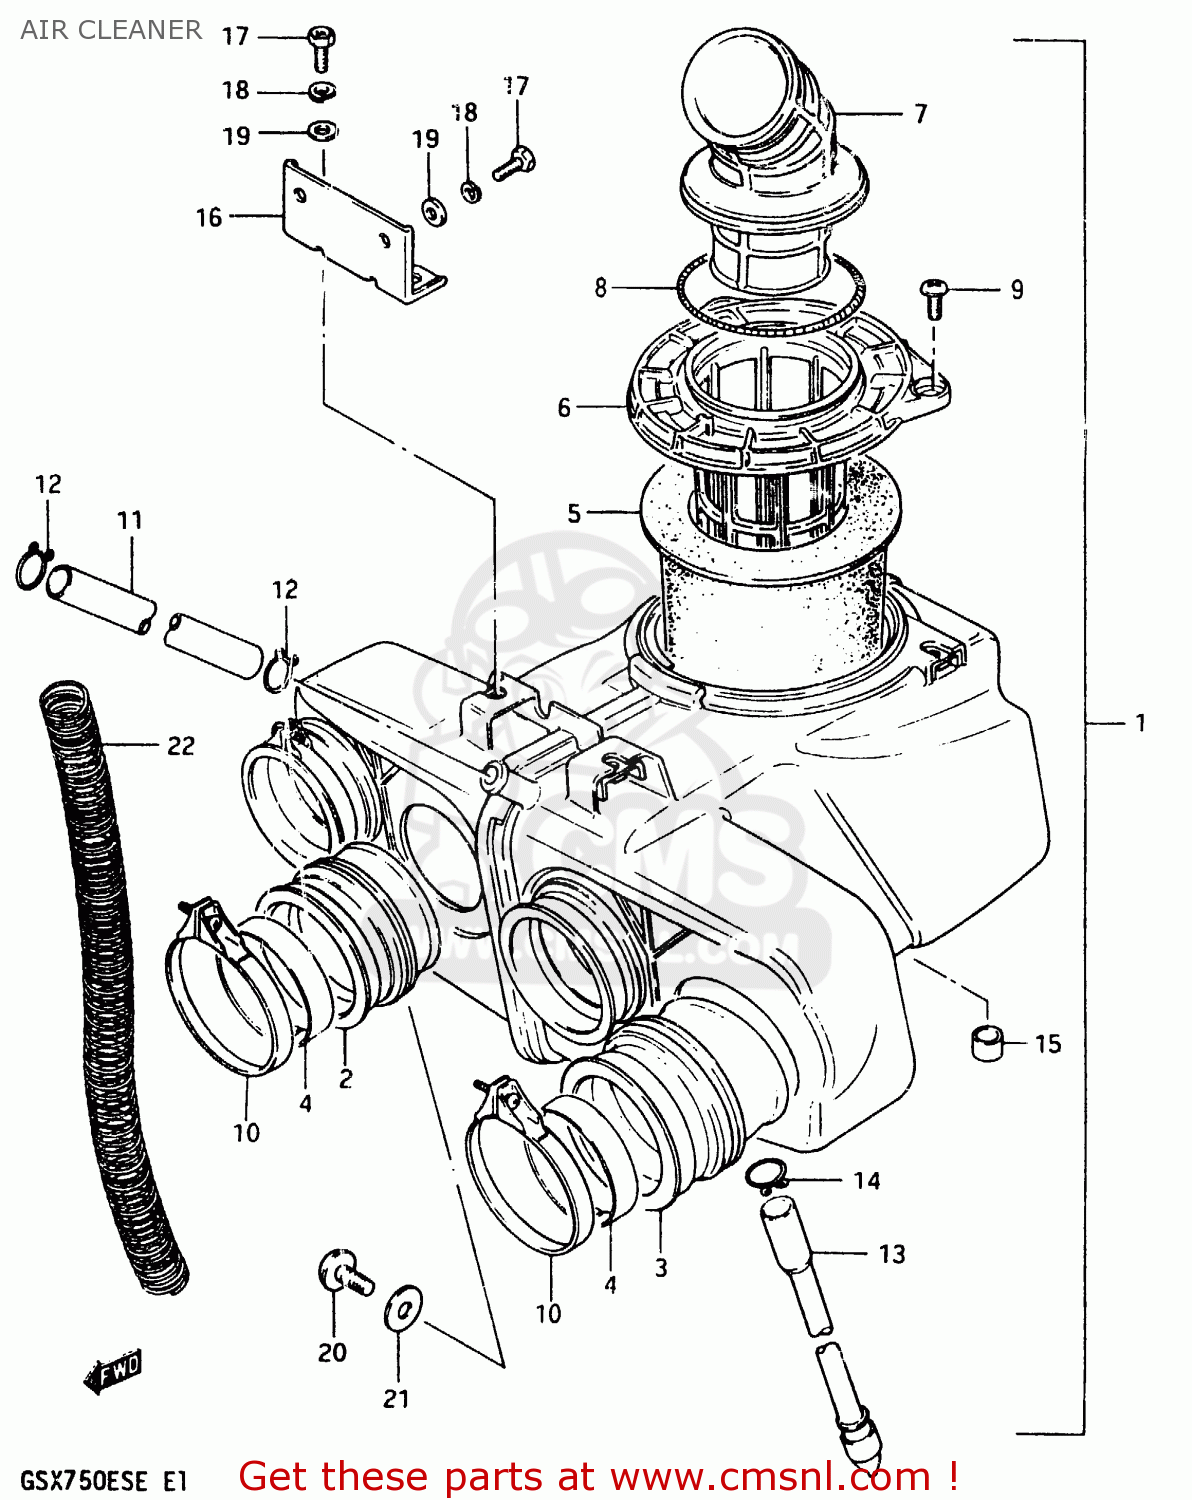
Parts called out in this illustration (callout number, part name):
1	CLEANER ASSEMBLY,AIR
2	TUBE,AIR CLEANER OUTLET
3	TUBE,AIR CLEANER OUTLET
4	RING,CARBURETOR AIR INLET HOSE
5	FILTER,AIR CLEANER
6	HOLDER,AIR FILTER
7	TUBE,AIR CLEANER INLET
8	CLAMP,INLET TUBE AIR CLEANER
9	SCREW
10	CLAMP
11	HOSE
12	CLIP
13	DRAIN TUBE
14	CLIP
15	FILTER,DRAIN
16	BRACKET,HOLDER
17	SCREW(6X12)
18	LOCK WASHER
19	WASHER
20	SCREW
21	WASHER
22	SPRING
